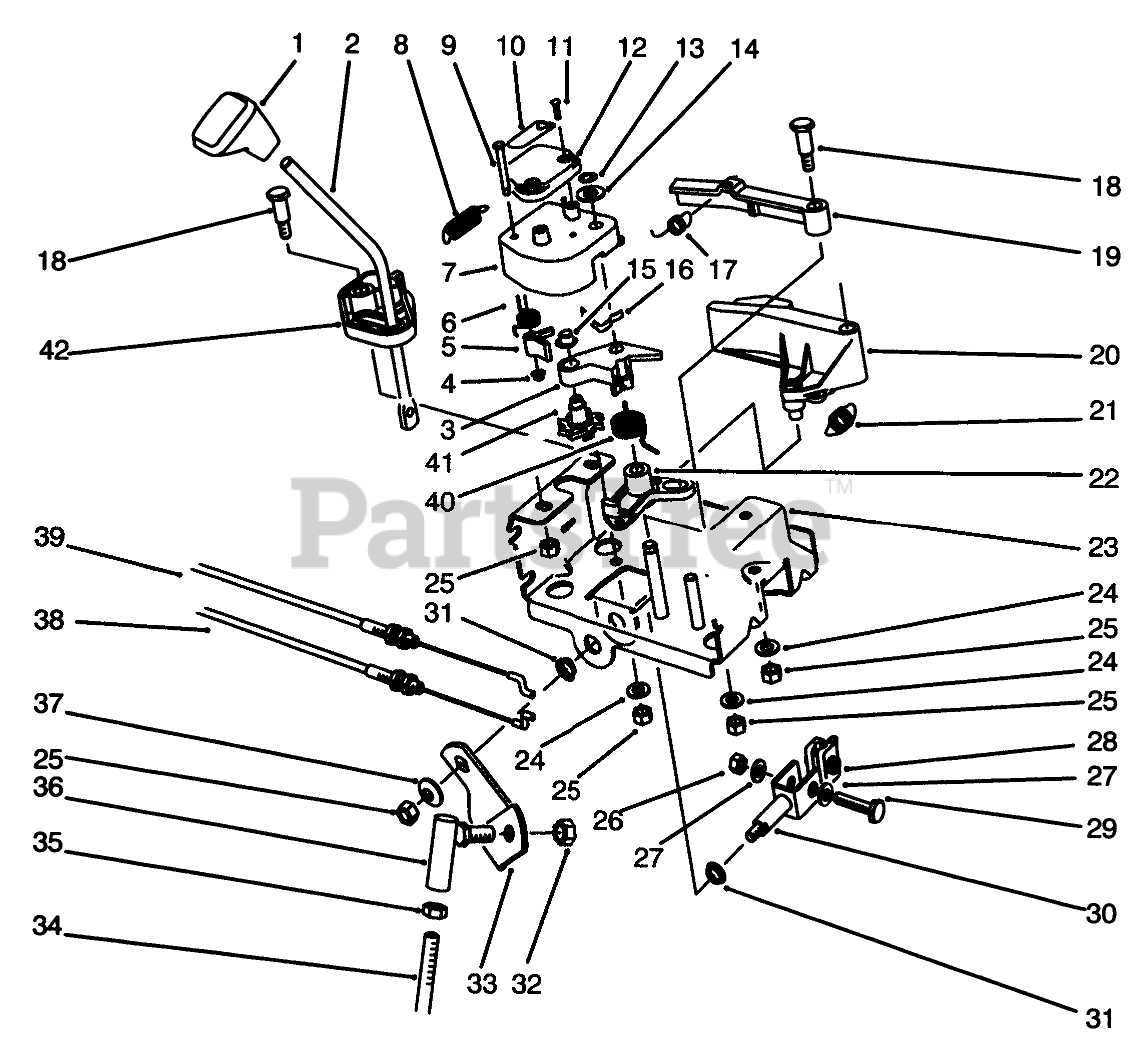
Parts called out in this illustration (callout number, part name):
1	KNOB-SHIFT
2	ROD-SHIFT
3	LEVER-WHEEL, INDEX
4	NUT-PUSH
5	TANG-INDEX
6	SPRING-TORSION
7	LATCH-LEVER
8	SPRING-EXTENSION
9	PIN-TANG
10	DECAL
11	SCREW-PPH
12	COVER-LATCH
13	RING-RETAINING
14	WASHER-THRUST
15	RETAINER-PUSH ON
16	SPRING-FLAT
17	SPRING-EXTENSION
18	SCREW-SHOULDER
19	LEVER-LOCKOUT
20	LEVER-REVERSE
21	SPRING-EXTENSION
22	LEVER-REVERSE, SWITCH
23	Frame-Control
24	WASHER-PLAIN
25	NUT-LOCK, NI
26	NUT-LOCK, NI
27	WASHER-FLAT
28	RETAINER-ROD, SHIFT
29	SCREW-HH
30	CLEVIS ASM
31	BUSHING
32	NUT-LOCK, NI
33	BRACKET-SHIFT
34	ROD-BENT SHIFT, LOWER
35	NUT-HJ
36	JOINT-BALL
37	WASHER-BELLEVILLE
38	CABLE-GEARBOX
39	CABLE-ARM, LATCH
40	SPRING-TORSION
41	WHEEL-INDEX
42	BASE-LOCKOUT
